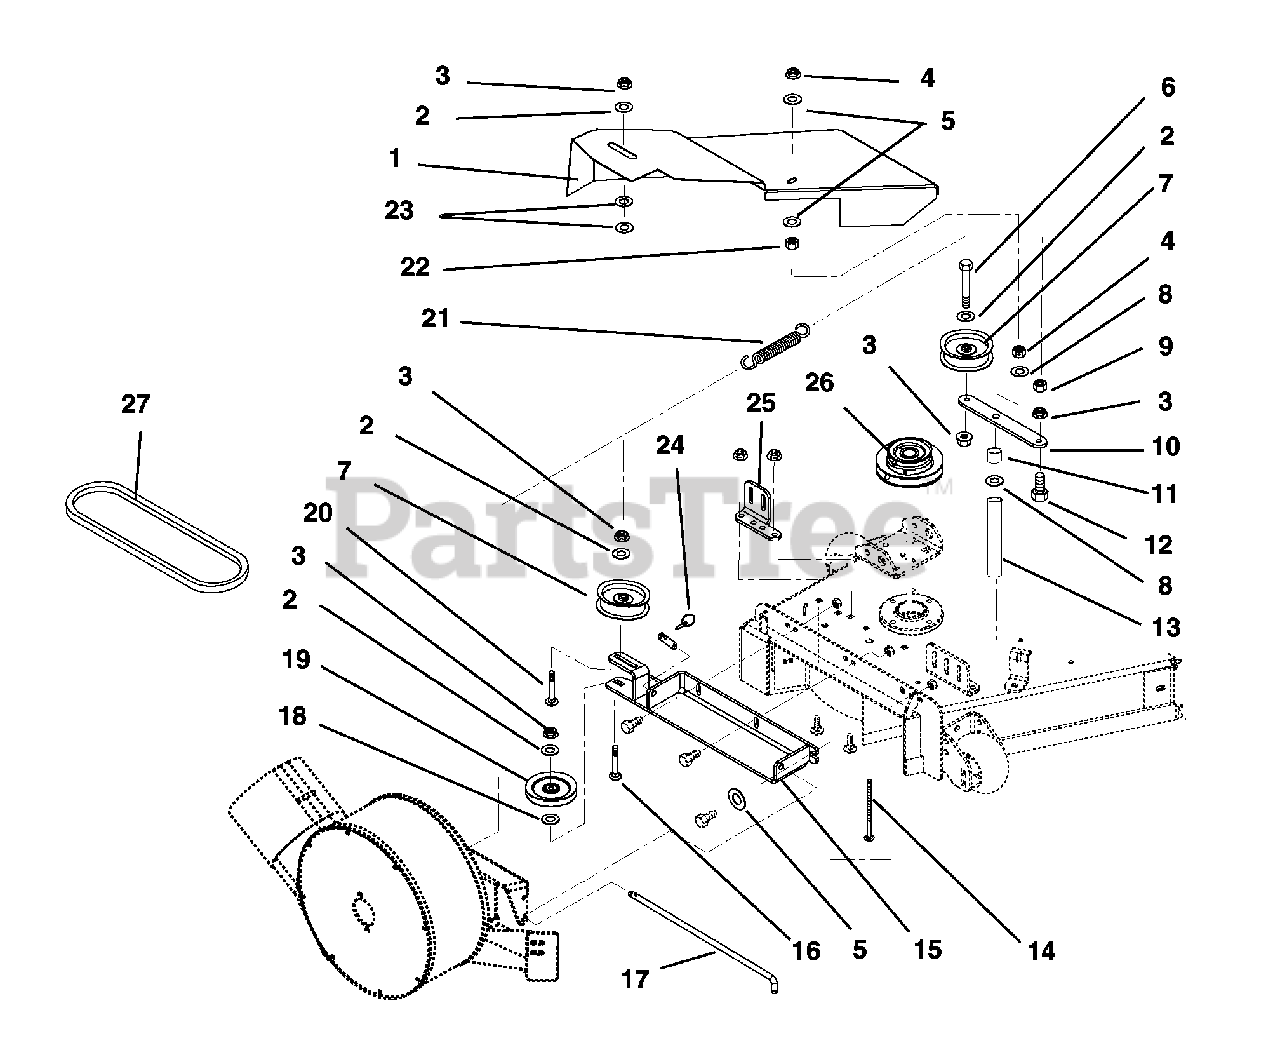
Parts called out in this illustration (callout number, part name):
1	Weldment, Belt Guard
2	Washer-Flat-Steel .438 x 1.00 x .083
3	Nut-Locking-Top-Flange .38-16
4	Nut-Locking-Top-Flange .31-18
5	Washer-Flat-Steel .38 x .875 x .083
6	Bolt-Hex .38-16 x 1.75 Grade 5
7	Idler Flanged 3.50
8	Washer-Flat-Steel .344 x 1.125 x .13
9	Nut-Locking-Center .38-16
10	Arm, Idler
11	Spacer .380 x .503 x .281
12	Bolt-Hex .38-16 x 1.25 Grade 5
13	Spacer .391 x .625 x 1
14	Bolt .312-18 x 4.00
15	Weldment, Pivot Mount 44,48,52
16	Bolt-Round Head Square Neck .38-16 x 1.75 Grade 5
17	Rod, Pivot
18	Washer-Flat-Steel .406 x 1.00 x .188
19	Idler-V 4.00 x .38
20	Bolt-Round Head Square Neck .38-16 x 2.50 Grade 5
21	Spring-Tension .080 x .687 x 5.16
22	Nut-Locking-Center .31-18
23	Washer-Flat-Steel .406 x 1.375 x .135
24	Pin-Klik 1.00 x .188 x 1.25
25	Bracket, 44- and 48-Inch Deck Mounting
25	Bracket, 52-Inch Deck Mounting
26	Pulley, Double V 3.50/5.25 Diameter
27	V-Belt, 44- & 48-Inch Mower Deck
27	V-Belt 52-Inch Mower Deck
